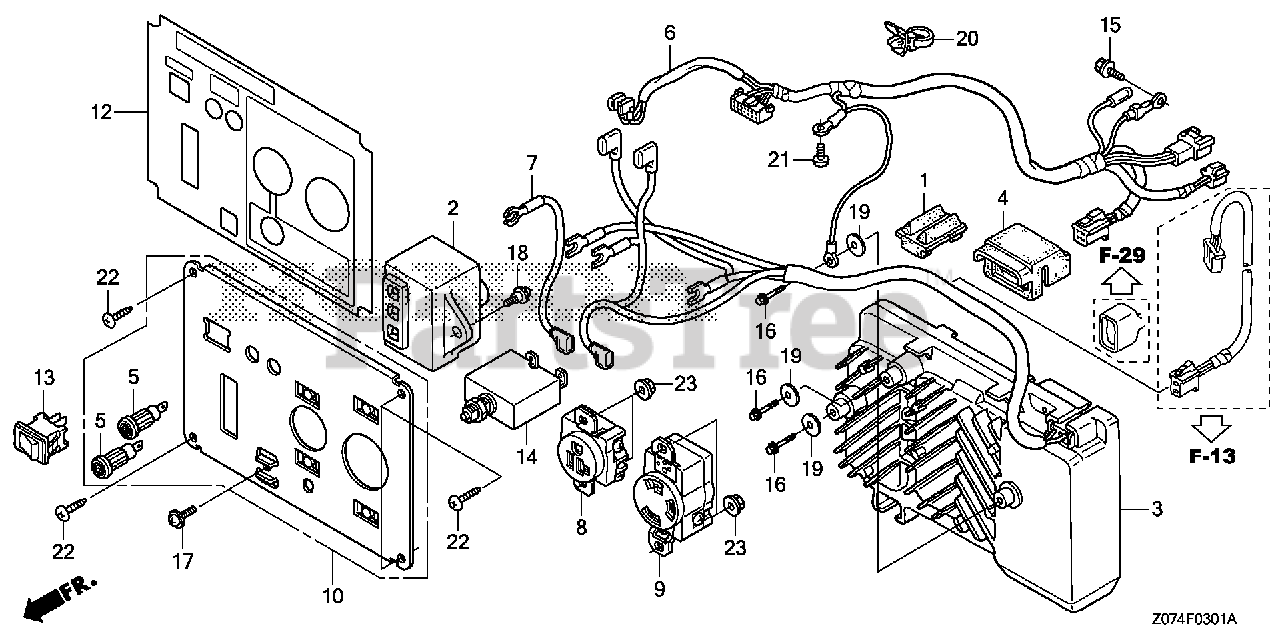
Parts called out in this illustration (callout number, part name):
1	RUBBER B, TANK MOUNTING
2	SPARK UNIT
3	INVERTER UNIT
4	COVER, CONNECTOR
5	SOCKET, COMPOSITE
6	WIRE HARNESS ASSY., CONTROL
7	WIRE, TERMINAL
8	RECEPTACLE (20A/125V)
9	RECEPTACLE (30A/125V)
10	PANEL, CONTROL
11	PANEL, CONTROL
12	MARK, CONTROL PANEL
13	SWITCH, AUTO-THROTTLE
14	PROTECTOR, CIRCUIT (20A) (WHITE)(TYCO)
15	BOLT, FLANGE (5X10)
16	BOLT, FLANGE (5X12)
17	SCREW, PAN (5X12)
18	SCREW, PAN (5X13)
19	WASHER, PLAIN (20MM)
20	BAND (100MM) (BLACK)
21	SCREW, PAN (5X8)
22	SCREW, TAPPING (5X16) (PO)
23	NUT, FLANGE (4MM)
